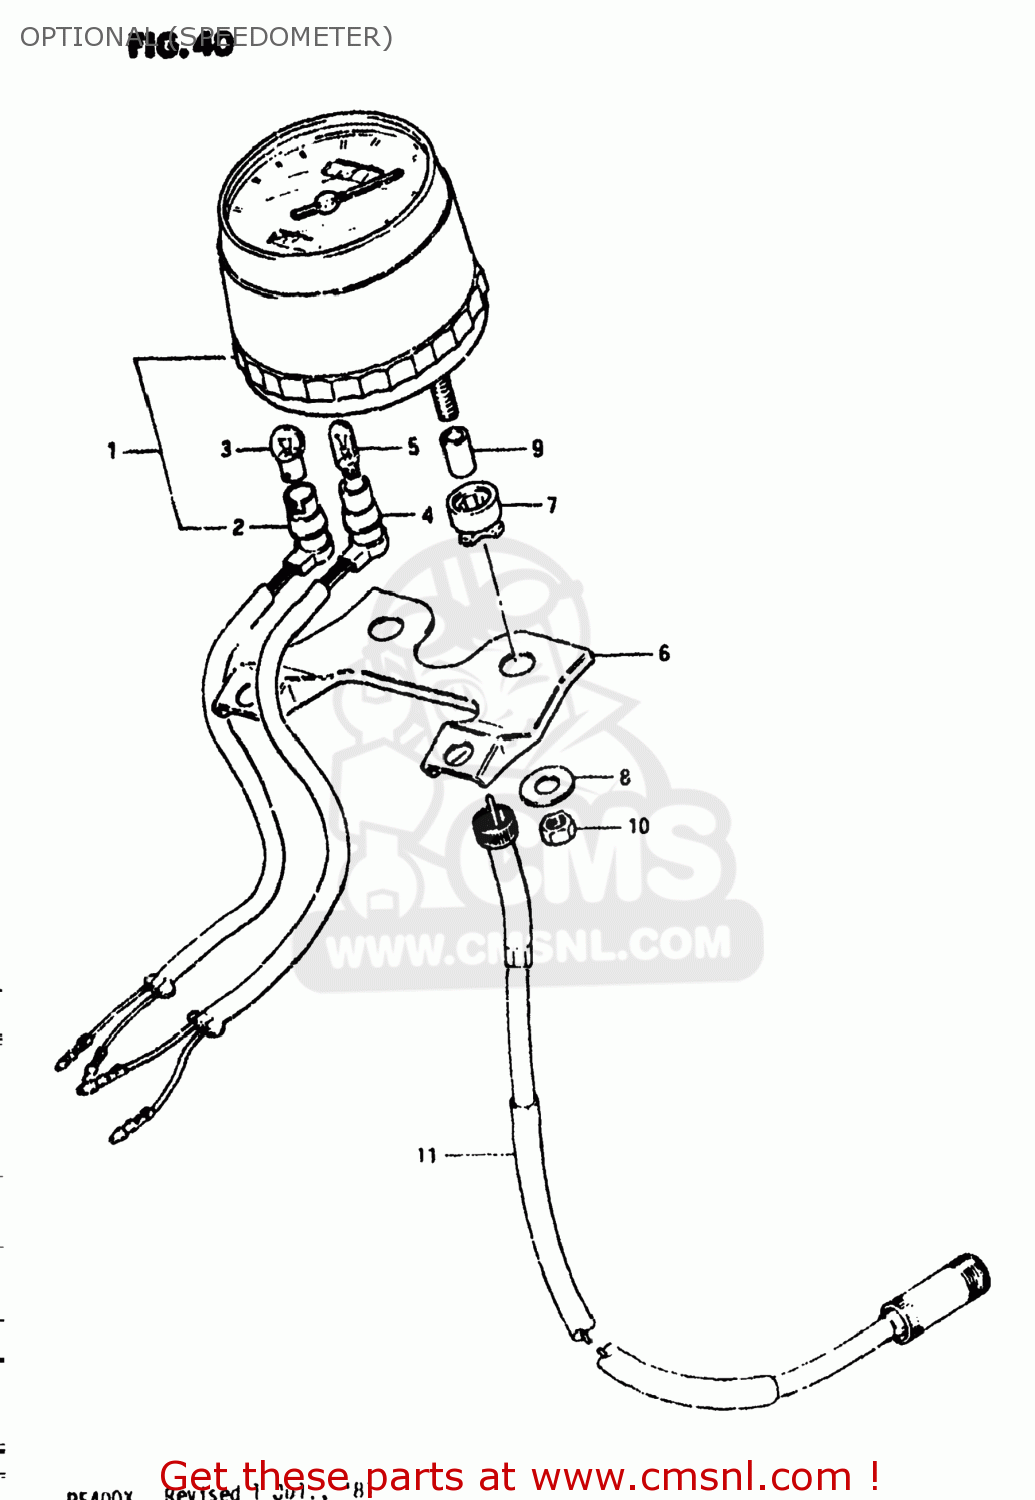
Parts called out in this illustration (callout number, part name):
1	SPEEDOMETER ASSEMBLY
2	SOCKET,METER
3	BULB(6V1.7W,STANLEY,A61A)
4	SOCKET,METER
5	BULB(6V1.7W,STANLEY,A61A)
6	BRACKET,SPEEDOMETER
7	CUSHION,SPEEDOMETER
8	WASHER
9	SPACER,METER
10	NUT
11	CABLE ASSEMBLY,SPEEDOMETER
